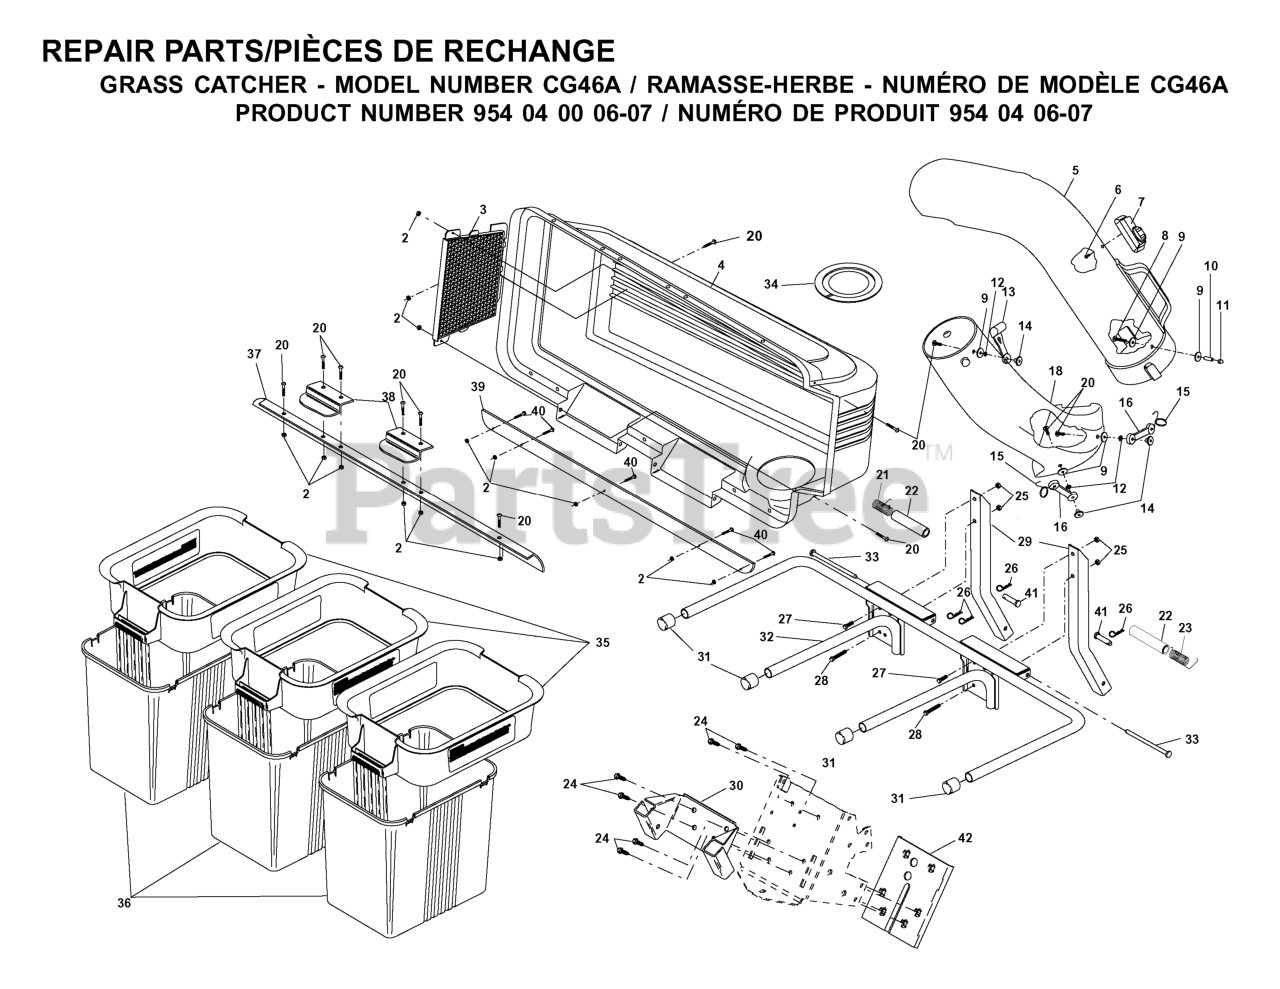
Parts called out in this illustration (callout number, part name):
3	COVER SCREEN
4	COVER BAGGER
5	CHUTE.UPPER.42"
7	INDICATOR DUMP BAG
8	SCREW
11	NUT
12	LOCKWASHER #10
13	LATCH.HOOD.
14	WELDNUT
15	HOOK LATCH
16	RUBBER LATCH
18	CHUTE.LOW.GT.46
20	SCREW
21	SPRING COVER LH
22	SPACER BAG 3-PIN
23	SPRING COVER RH
24	BOLT 7/16-14X3/4
25	LOCKNUT
26	RETAINER-SPRNG RB
27	BOLT
28	Bolt Fin Hex 5/16-18 UNC x 2-1/4
29	POST SUPT BAGGER
30	BRACKET MTG
31	TUBING PLUG
33	HINGE PIN
34	GASKET.COVER.BAGGER
35	CONTAINER TOP
36	CONTAINER BOTTOM
37	BAGGER TOP SEAL
38	LATCH CER38
39	STRIP.REINFORCEMENT.3.BIN.
40	Screw, #10-24 x 1/2
41	PIN CLEVIS
42	PLATE REINF MTG
